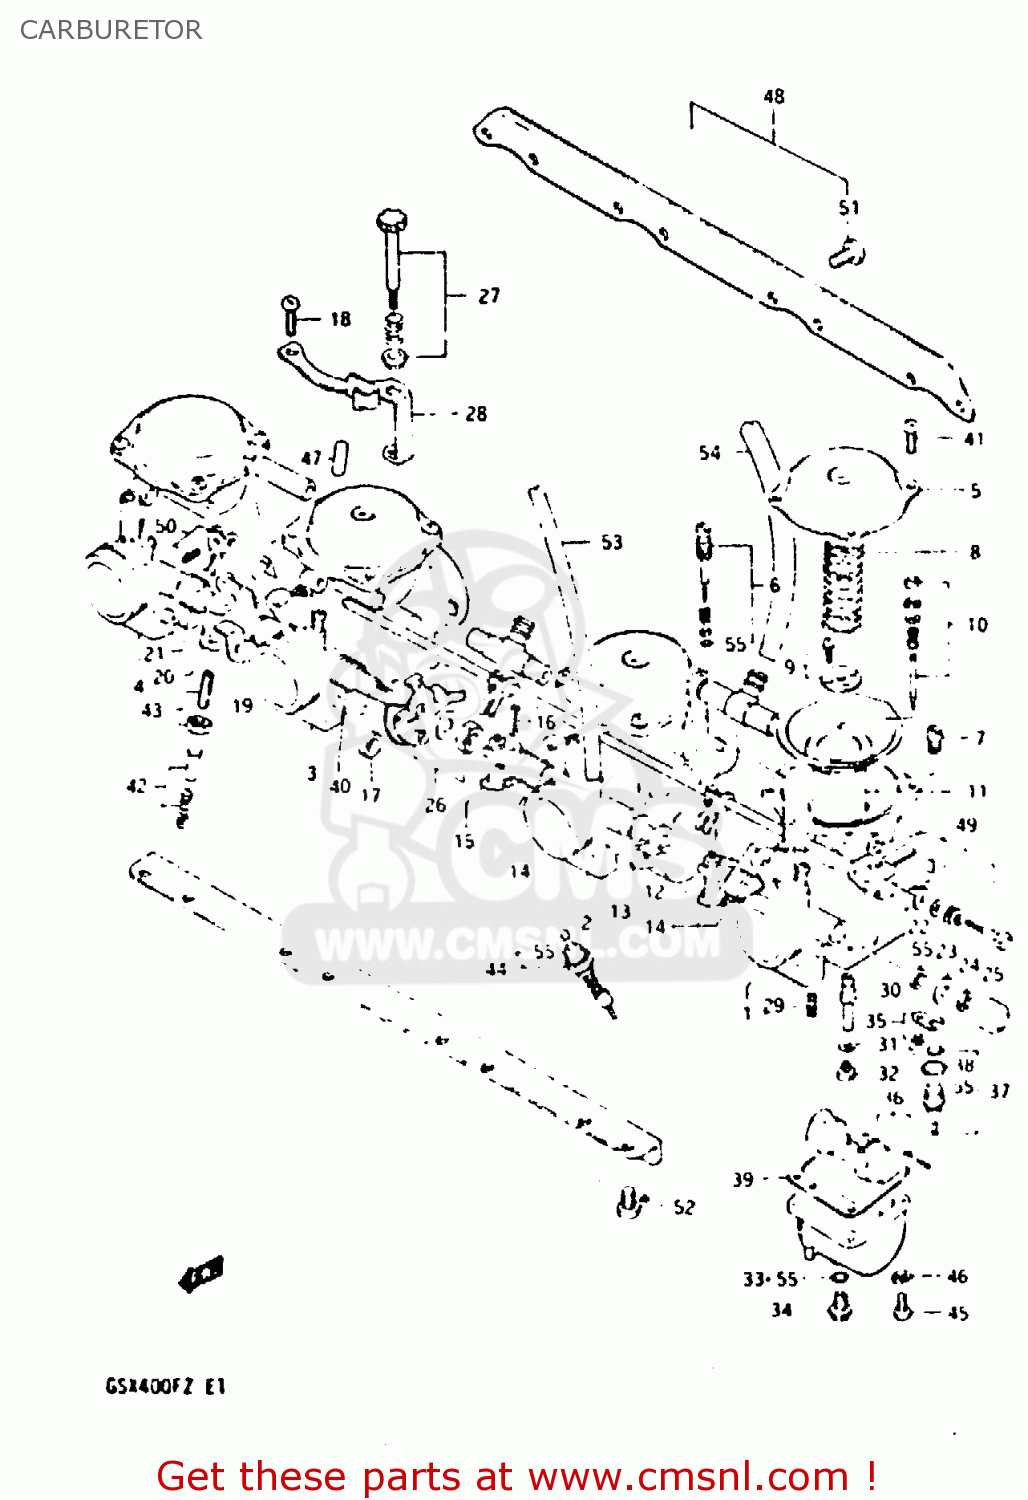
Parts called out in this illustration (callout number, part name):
1	CARBURETOR, NO. 1
2	CARBURETOR, NO. 2
3	CARBURETOR, NO. 3
4	CARBURETOR, NO. 4
5	COVER
6	ADJUSTER SET
7	JET
8	SPRING
9	PLATE SET
10	JET NEEDLE SET
11	DIAPHRAGM ASSEMBLY
12	SHAFT, THROTTLE
13	SHAFT, THROTTLE
14	SPRING
15	LEVER, THROTTLE
16	PIN,THROTTLE SHAFT
17	SPACER,THROTTLE SHAFT
18	SCREW
19	SHAFT, THROTTLE
20	SHAFT, THROTTLE
21	SPRING
22	SEAL
23	GASKET,THROTTLE SHAFT (NAS)
24	E RING
25	CAP
26	THROTTLE LEVER SET
27	IDLE ADJUSTER SET
28	BRACKET, IDLE ADJUSTER
29	JET
30	JET, NEEDLE (P-O)
31	WASHER,NEEDLE NOZZLE
32	JET
33	GASKET (NAS)
34	PLUG,DRAIN
35	PLATE
36	FLOAT SET
37	VALVE ASSY,NEEDLE
38	O-RING,NEEDLE VALVE
39	GASKET,FLOAT CHAMBER (NAS)
40	SPRING,THROTTLE SHAFT
41	SCREW
42	SPRING SET
43	SCREW SET
44	STARTER PLUNGER SET
45	SCREW
46	LOCK WASHER
47	CAP
48	FLANGE SET
49	SCREW SET
50	STARTER LEVER SET
51	SCREW
52	SCREW 6X12
53	HOSE
54	HOSE
55	GASKET SET (NAS)
